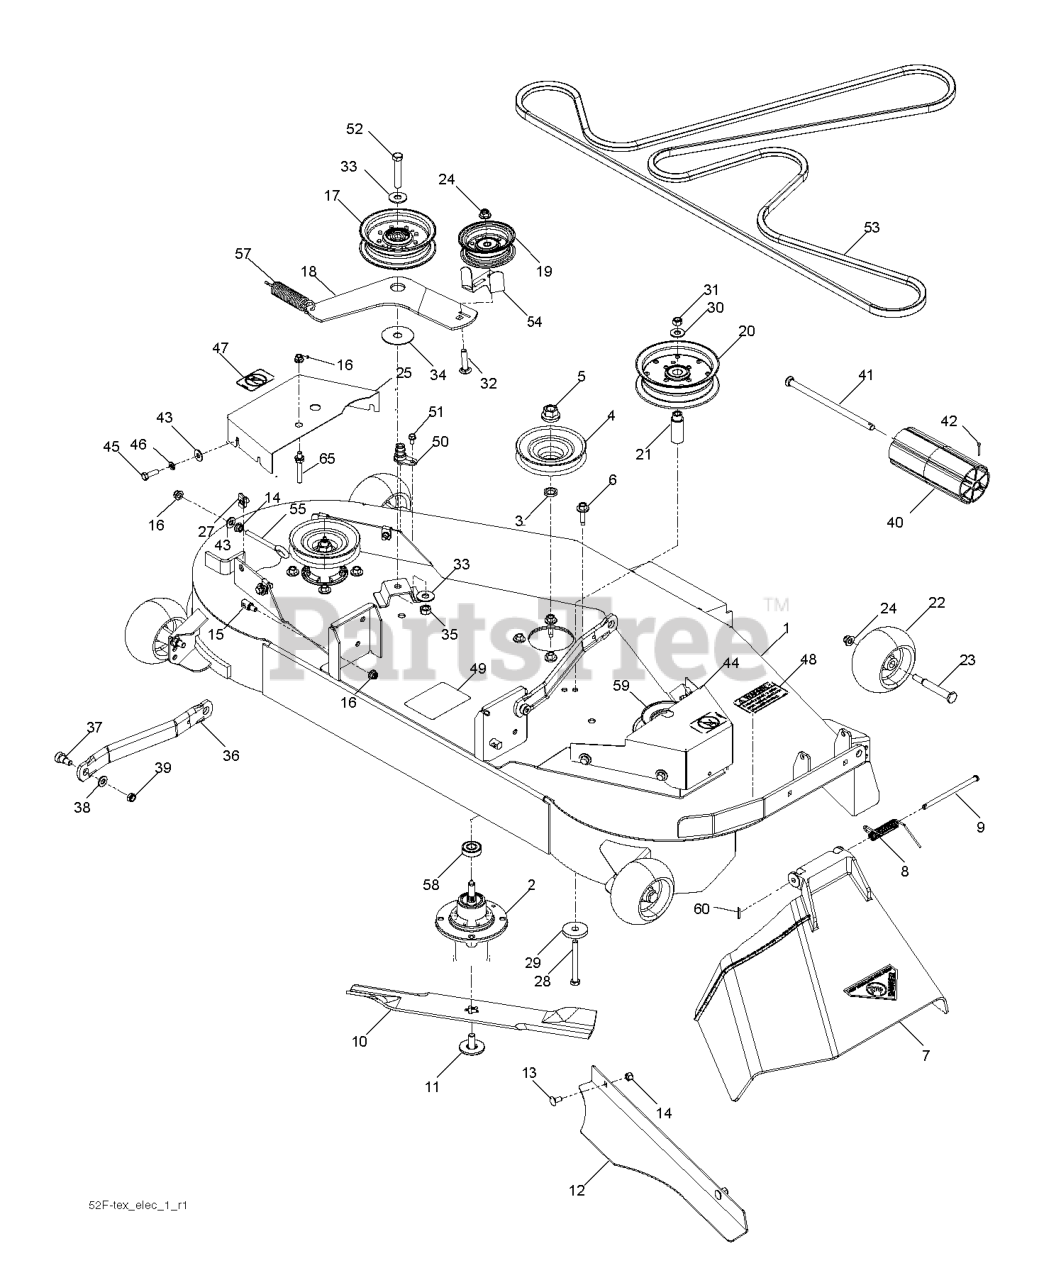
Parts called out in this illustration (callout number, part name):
1	DECK SVC W/DECALS.52.GTH.ORG
2	MANDREL.DECK.ASSEMBLY
3	WASHER.SPACER.MANDREL
4	PULLEY.DRIVEN.DECK.48'
5	NUT.FLANGE.LOCK.TOP
6	SCREW, WASHER HEAD
7	DISCHARGE CHUTE 52"
8	SPRING - TORSION
9	PIN-CLEVIS 5/16 DIA X 5.19 ZD
10	BLADE, 17.75 X 2.5 X .25
11	BOLT.WASHER.ASM.7/16-2
12	PLATE.52".CONFINEMENT.BLACK
13	BOLT.CARR.5/16-18X5/8.SHORT
14	NUT.71038.31-18.HEX.NYLOCK
15	STUD.FASTNER.W/ANTI-ROTATE
16	5/16-18 NYLOC FLANGE NUT
17	PULLEY.IDLER.MWR.STATI.LH
18	ARM, IDLER, 52" BLK
19	PULLEY.IDLER.FLAT
20	PULLEY, IDLER
21	BUSHING, IDLER
22	GAUGE WHEEL
23	BOLT.SHOULDER.3/8-16X3-5/8.
24	NUT 3/8-16 HEX FLG NYLOC ZD
25	SHIELD.BELT.LH.ORANGE
27	U-CLIP 5/16-18 NUT RETAINER
28	HCS 3/8-16 X 3-1/2 GR5 ZD
29	SPINDLE WASHER
30	RP WASHER 3/8 FLAT
31	NUT 3/8-16 NYLOC
32	RHSNB 3/8-16X1-3/4
33	WASHER 7/16 FLAT ZD
35	NUT.LOCK.FLANGE.7/16
36	ARM.SUSPENSION.MOWER
37	SB 3/8-16 X 3/8 SKT HD ZD
38	WASHER
39	NUT HEX 3/8-16 NYLON, THIN
40	NOSE ROLLER 48"
41	ROD.ROLLER.NOSE.NARROW.48"
42	PIN.COTTER.5/16.BOW TI
43	WASHER.5/16.FLAT.STE.STD.
44	SHIELD.BELT.RH.52.ORANGE
45	BOLT.FIN.HEX.5/16-18UNC X 1.00
46	WASHER.LOCK.HVY.HLCL.SPR.5/16
47	DECAL, NO STEP
48	DECAL, CAUTION
49	DECAL.MOWER.SCH.48/54
50	PORT.WASHOUT
51	SCREW
52	BOLT.HEX.7/16-14
53	BELT, 143.5" EL
54	GUARD, BELT
55	EYE BOLT 5/16 X 3.50
56	NUT 5/16C WHIZ
58	BEARING, BALL
59	RP PULLEY, COLLECTION 48
60	RETAINER CLIP
61	ROD.ANTI.SWAY.48/54"K4
62	WASHER
251	KEEPER.BELT.ENGINE
